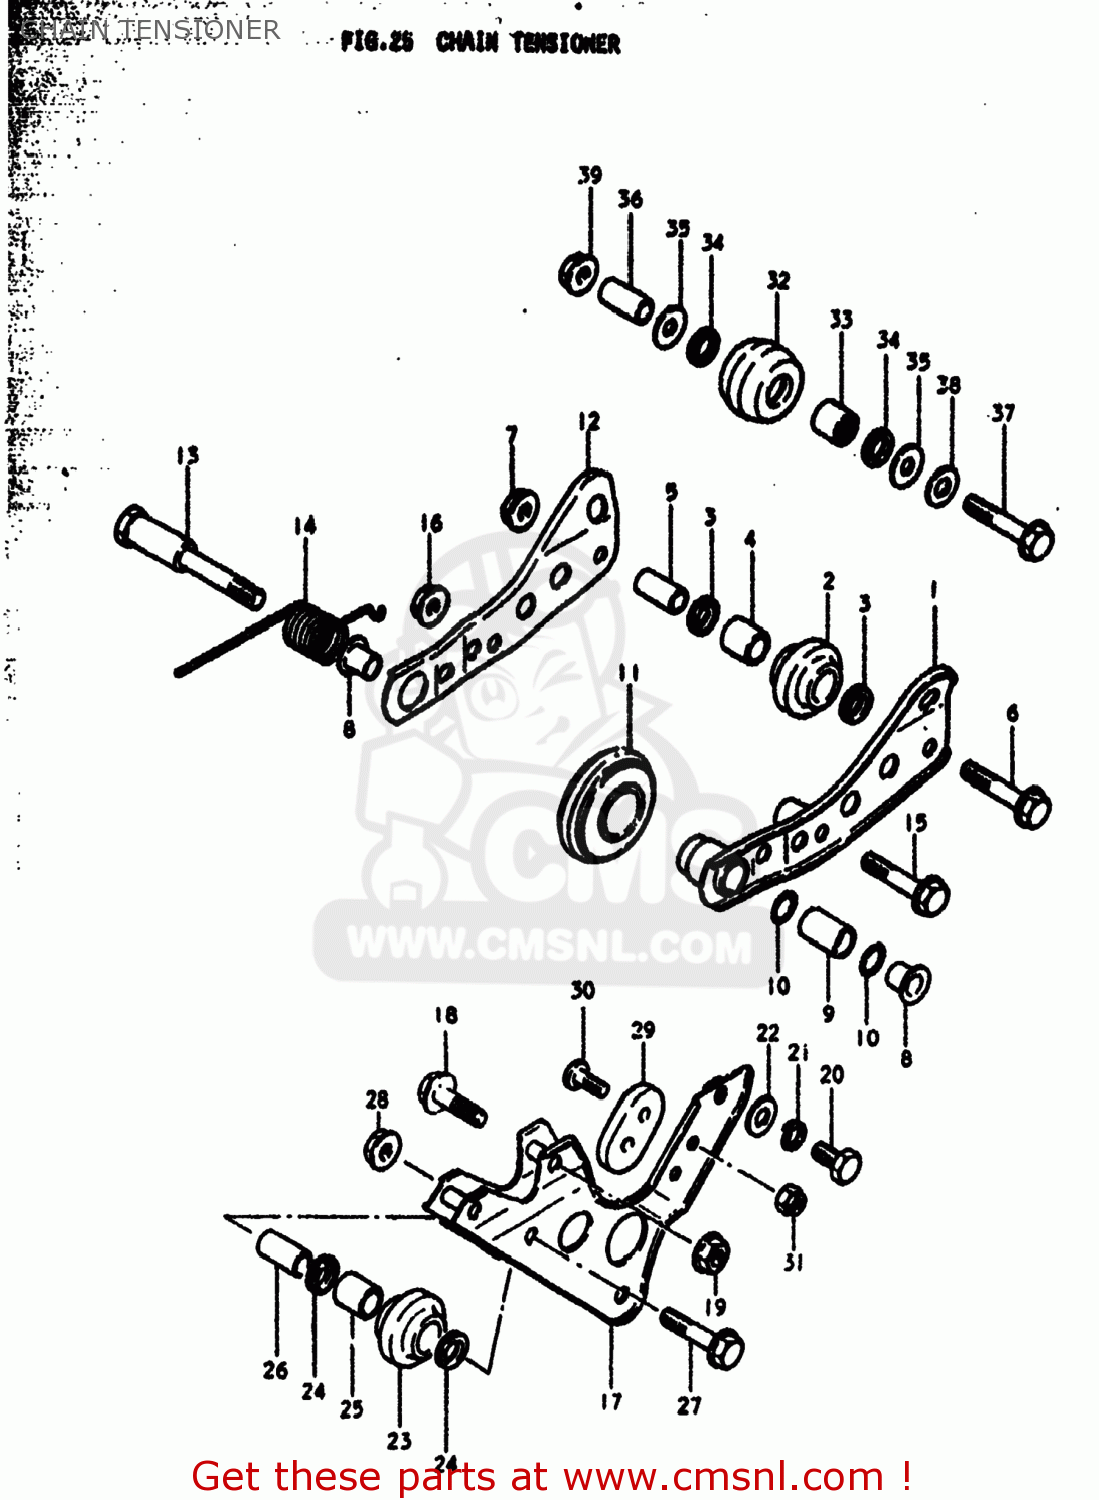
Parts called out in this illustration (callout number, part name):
1	TENSIONER,CHAIN
2	ROLLER,CHAIN TENSIONER LWR
3	SEAL,OIL(10X14.4X3.5)
4	SPACER,CHAIN GUIDE
5	SPACER(6.2X10X22.5)
6	BOLT 6X35
7	NUT
8	SPACER,CHAIN TENSIONER
9	BUSHING,CHAIN TENSIONER
10	O RING(D:1.3,ID:9.6)
11	ROLLER,CHAIN GUIDE
12	PLATE,CHAIN TENSIONER
13	BOLT
14	SPRING
15	BOLT 6X35
16	NUT
18	BOLT
19	NUT 6MM
20	BOLT(6X14)
21	LOCK WASHER
22	WASHER
23	ROLLER,CHAIN TENSIONER LWR
24	SEAL,OIL(10X14.4X3.5)
25	SPACER,CHAIN GUIDE
26	SPACER(6.2X10X22.5)
27	BOLT 6X35
28	NUT
29	PAD
30	SCREW
31	NUT
32	ROLLER,CHAIN GUIDE
33	BEARING(10X14X15)
34	SEAL,OIL(10X14.4X3.5)
35	WASHER
36	SPACER(6.2X10X22.5)
37	BOLT
38	WASHER
39	NUT 6MM
